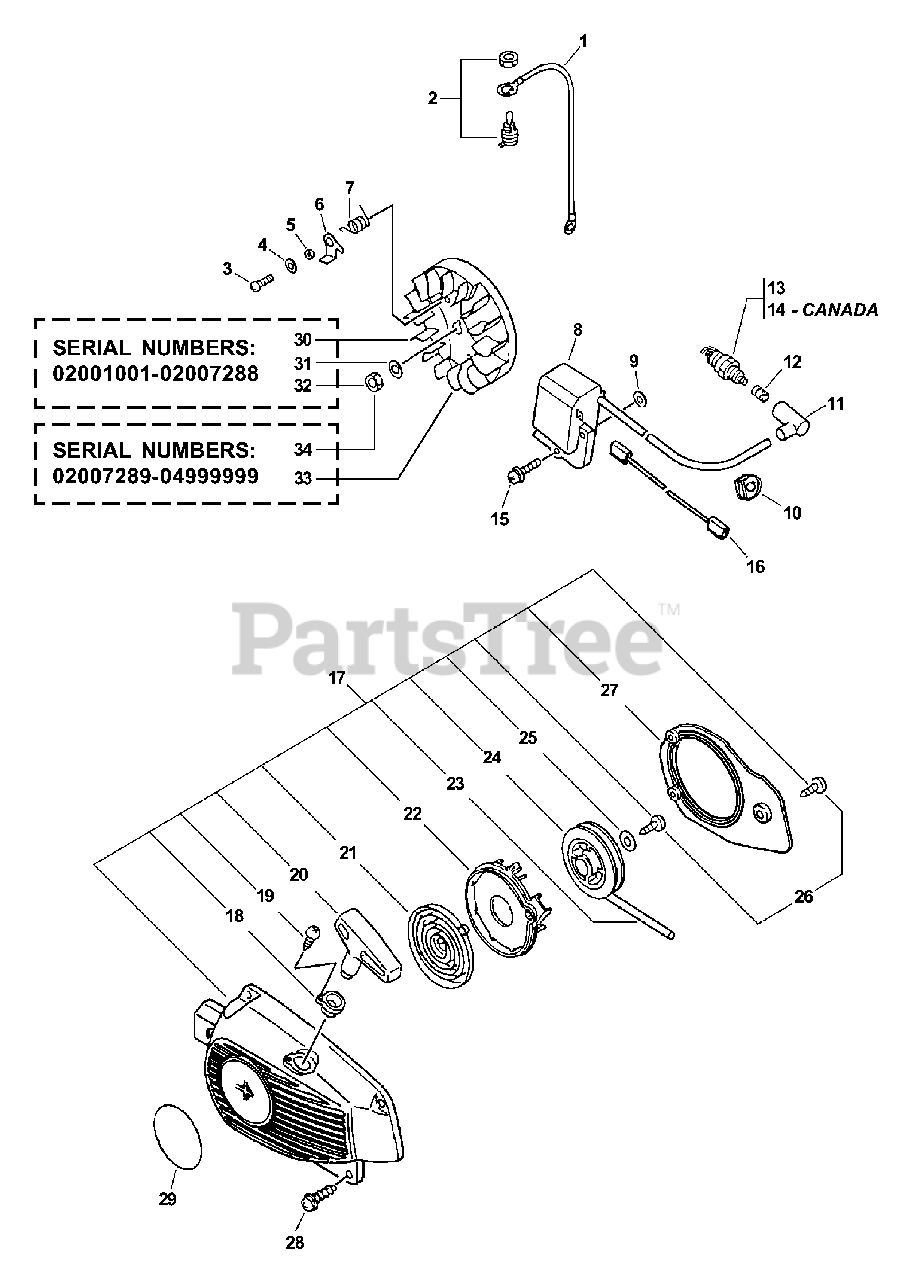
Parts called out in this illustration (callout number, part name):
1	LEAD - GROUND
2	IGNITION SWITCH KIT
3	SCREW - 5X12
4	WASHER - 5
6	PAWL, STARTER
7	SPRING, RETURN
8	COIL, IGNITION
11	CAP, SPARK PLUG
12	TERMINAL, SPARK PLUG CAP
13	SPARK PLUG -- BPM-8Y
14	SPARK PLUG -- BPMR-8Y
15	SCREW - 5X22
16	LEAD - IGNITION
17	STARTER ASSY
18	GUIDE, ROPE
19	SCREW - 3X14
20	GRIP, STARTER
21	REWIND SPRING ASSY
22	PLATE, STARTER
23	ROPE, STARTER - 3X850
24	REEL, ROPE
26	SCREW - 4X14
28	SCREW - 4X16
29	LABEL - ECHO
30	FLYWHEEL
31	WASHER - 8
32	NUT - 8
33	FLYWHEEL
34	NUT - 8 -- FLANGE
